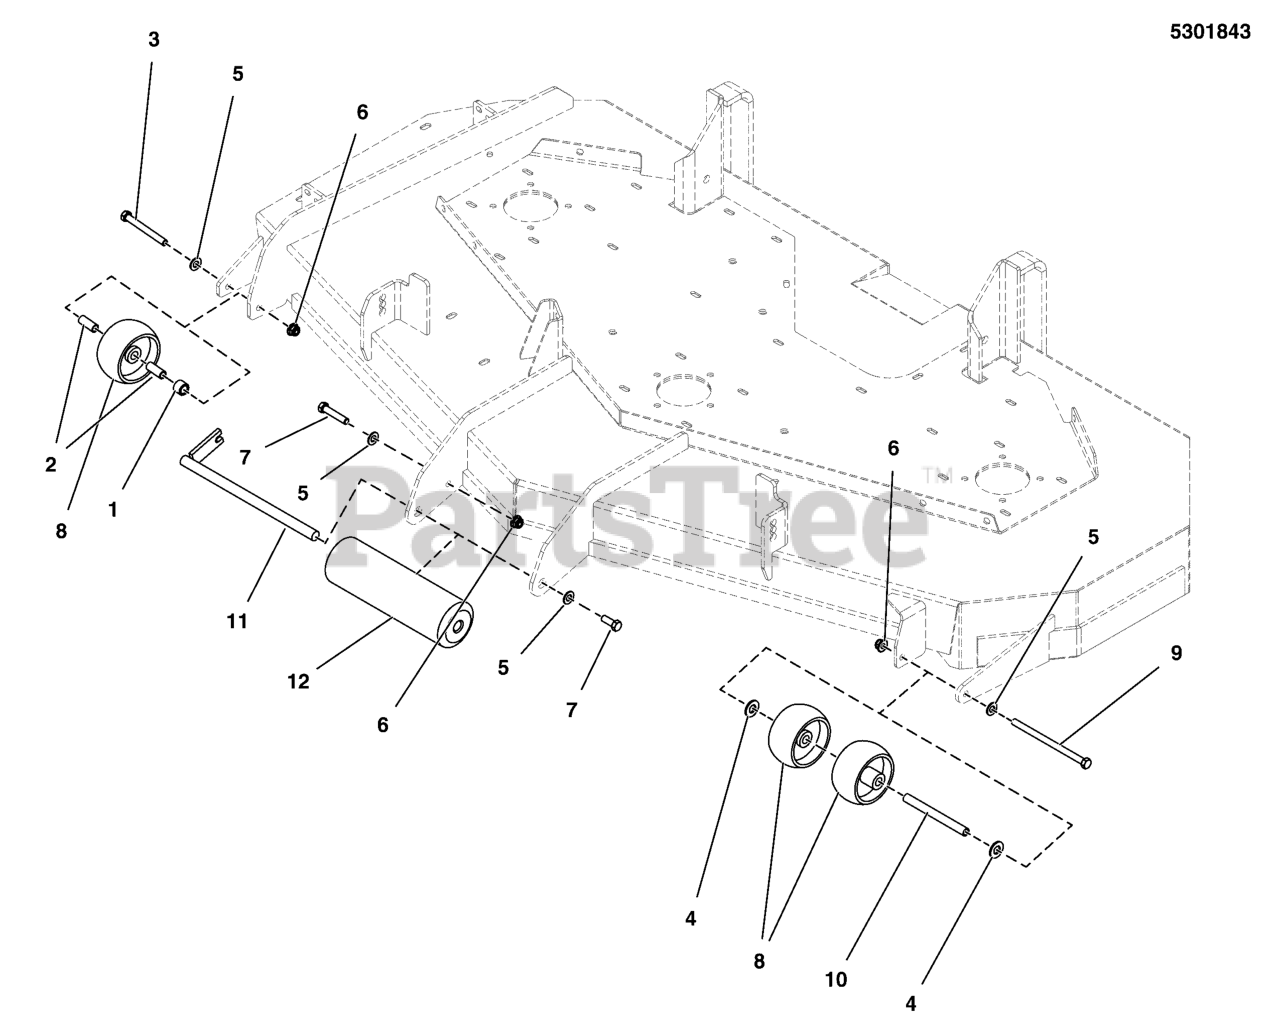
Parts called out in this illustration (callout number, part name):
1	SPACER, .51 X .75 X .56, PM, CZ
2	SPACER, .38 X .50 X 1.25, CZ
3	BOLT, 3/8-16 X 3-1/2" GD5 CZ
4	WASHER, 1/2" GD9 YZ
5	WASHER, 3/8 SAE
6	NUT, 3/8 - 16 HEX NYLOCK FLANGE
7	BOLT, 3/8-16 X 1" GD5 CZ
8	WHEEL- 2.00 WIDE 3.88 DIA 0.531ID POLY
9	BOLT, 3/8-16 X 6" GD5 CZ
10	SPACER, .38 X .50 X 5.06, CZ
11	PIN, ROLLER, CZ
12	ROLLER, DECK
